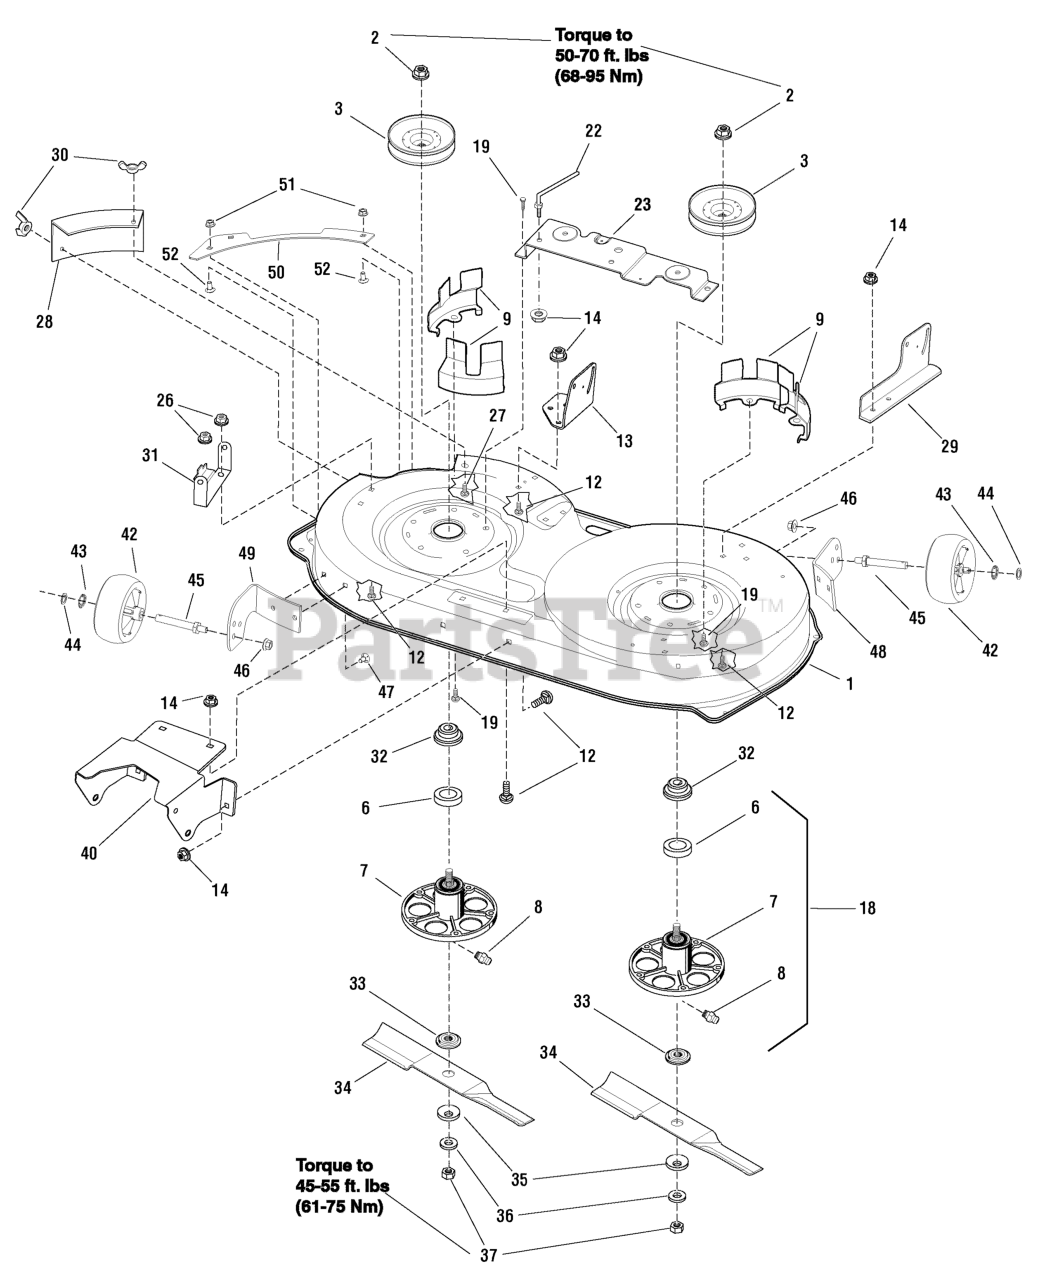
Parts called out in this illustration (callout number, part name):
1	HOUSING, Mower 42 in
2	NUT, Nylock, Pulley 9/16-18
3	PULLEY, Jackshaft
6	BALL BEARING, Jackshaft
7	JACKSHAFT HOUSING
8	FITTING, Lubrication
9	SEGMENT, Belt Guide
12	BOLT Carriage, 5/16-18 x 5/8
13	BRACKET, Right Suspension
14	NUT, Hex Flange 5/16-18
18	JACKSHAFT HOUSING ASSEMBLY
19	SCREW, 3/8-16 x 1-1/4
22	BELT GUIDE (5/16-18)
23	BRACKET, Brake Mounting 42 in
26	NUT, Hex Flange Lock, 5/16-18
27	BOLT, Carriage 5/16-18 x 3/4
28	COVER, Mulch
29	BRACKET, Left Suspension
30	WINGNUT, 5/16-18
31	BRACKET, Hinge
32	SPACER, Pulley
33	BLADE ADAPTER
34	BLADE, 42 in
35	WASHER, Belleville
36	WASHER, Hardened
37	NUT, Blade 9/16-18
40	BRACKET, Front Hanger
41	PLUG, Hole, .44" OD
42	WHEEL, Gauge
43	WASHER, FLAT, .81 X .550 X 16GA
44	CLIP, Hair Pin
45	BOLT, Gauge Wheel
46	NUT, Flange Lock, 3/8-16
47	BOLT, Carriage, 5/16-18 x 5/8
48	Bracket, Left Wheel
49	Bracket, Right Wheel
50	PLATE, Rear
51	BOLT, Carriage, 5/16-18 x 5/8
52	NUT, Hex Flange Whiz Lock, 5/16-18
